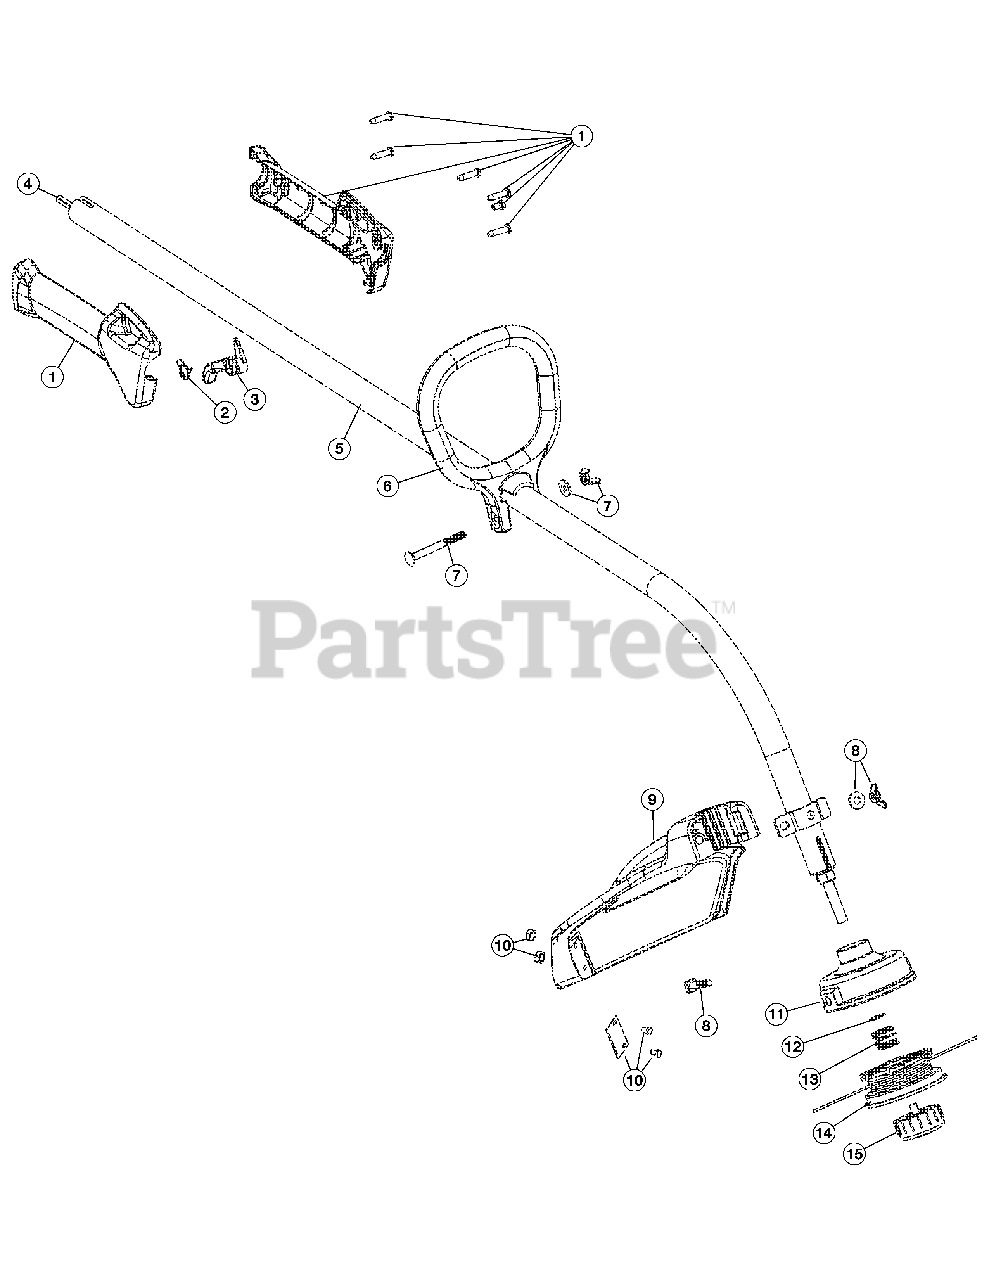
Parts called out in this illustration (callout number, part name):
1	Throttle Housing Assembly (includes 2 & 3)
2	Throttle Trigger Spring
3	Throttle Trigger
4	Flexible Drive Shaft
5	Drive Shaft Housing (includes 4 & 12)
6	D-Handle Assembly (includes 7)
7	D-Handle Hardware
8	Guard Mounting Hardware
9	Guard (includes 10)
10	Blade Assembly
11	Outer Reel (includes 12)
14	Inner Reel (line not included)
